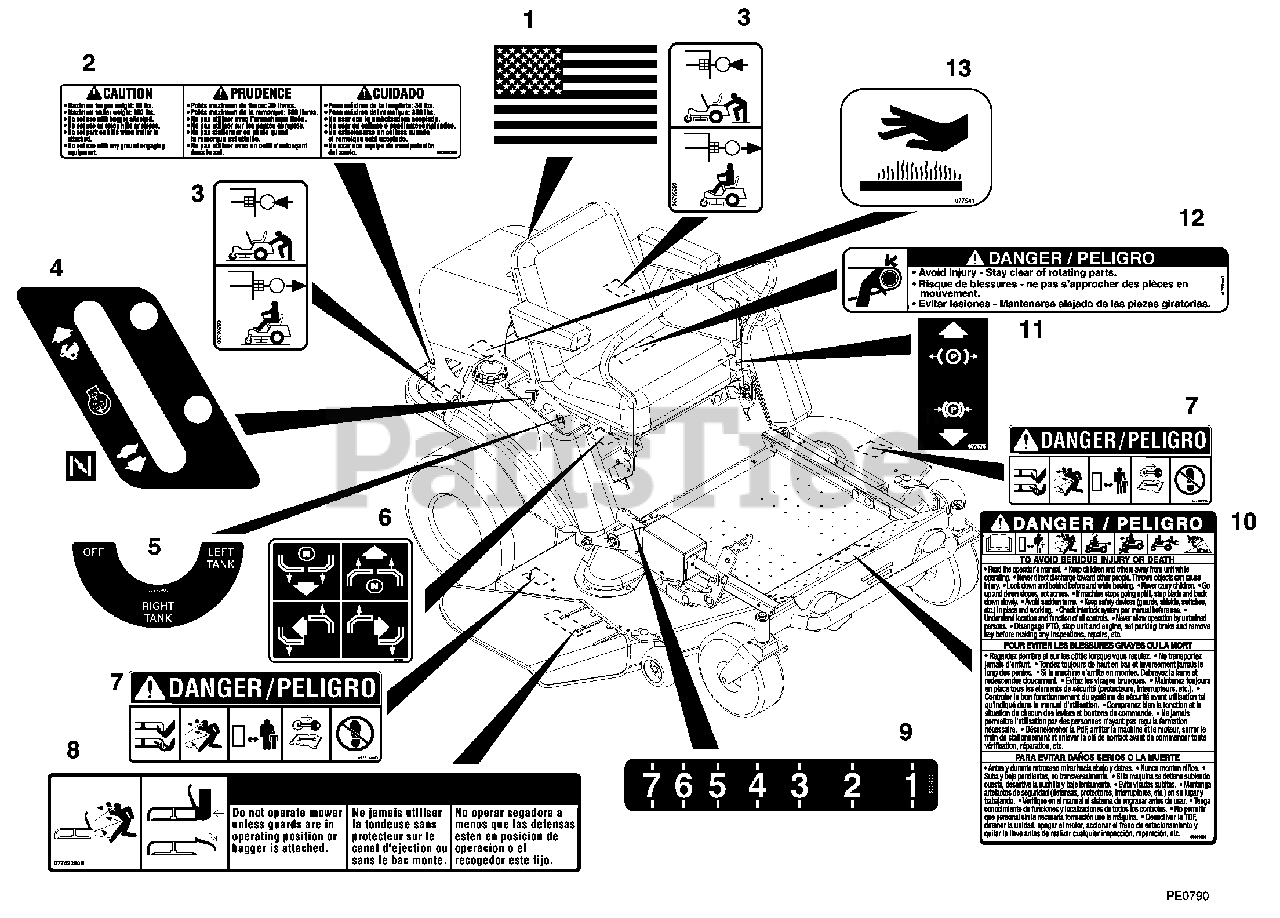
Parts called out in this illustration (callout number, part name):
1	Decal, American Flag
2	Decal, Trailer Hitch
3	Decal, Transmission Disconnect
4	Decal, Control
5	Decal, Fuel Value
6	Decal, Instructional Steering
7	Decal, Mower Pan Head Danger
8	Decal, Warning
9	Decal, Cut Height Zoom
10	Decal, Bilingual Danger
11	Decal, Parking Brake Lever
12	Decal, Danger
13	Decal, Hot Surface
